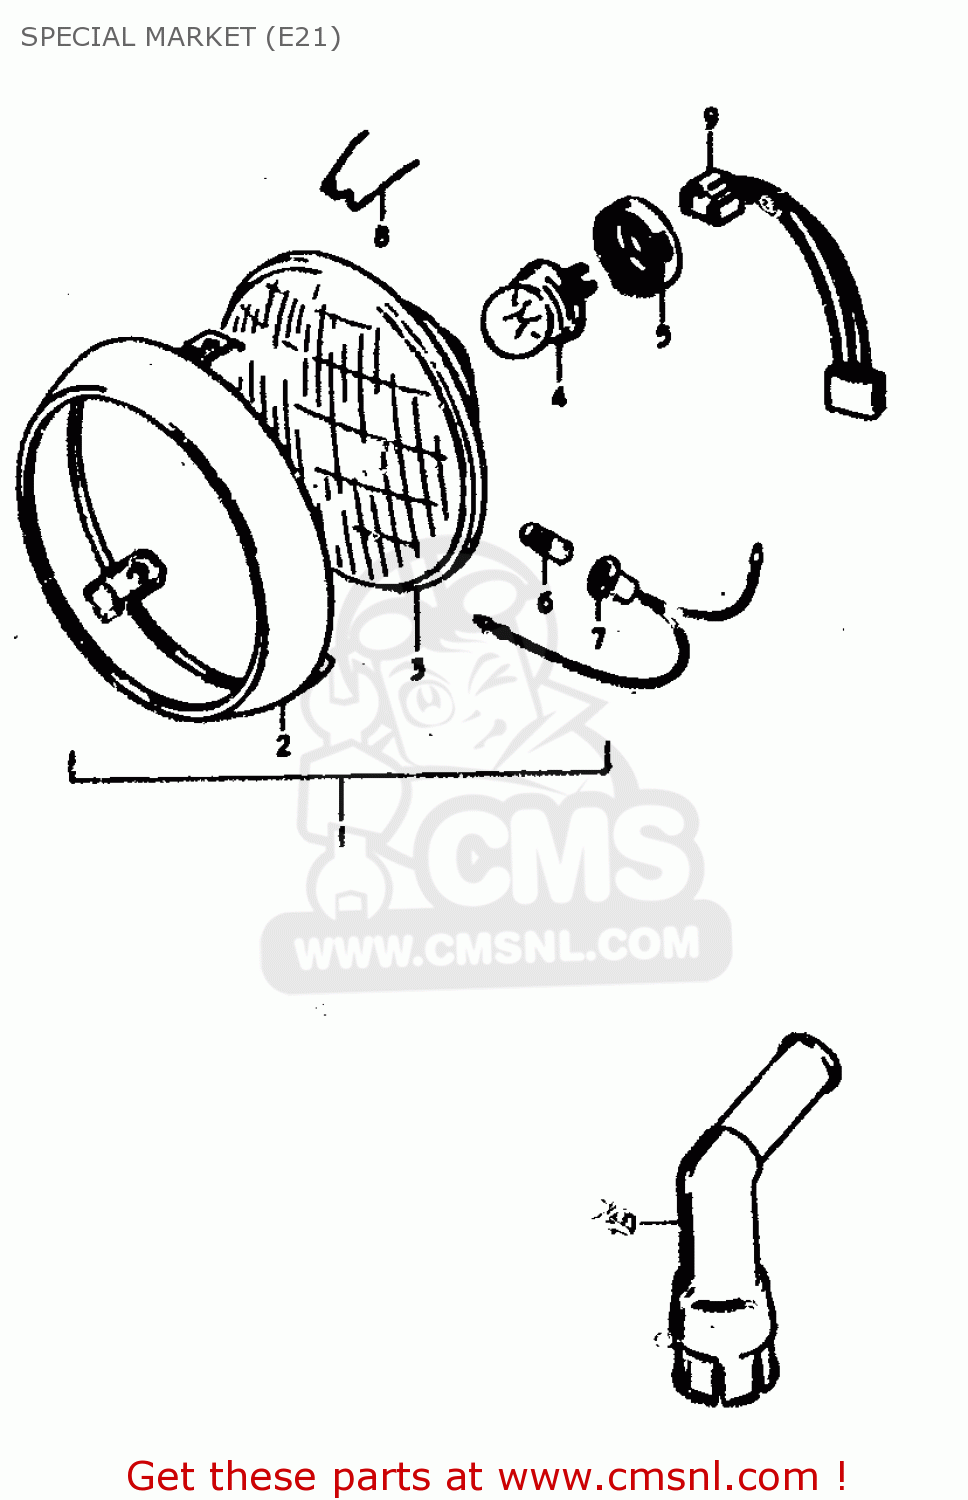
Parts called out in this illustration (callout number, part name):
1	HEADLAMP ASSY
2	RIM
3	UNIT
4	BULB(12V45/40W)
5	SETTER,BULB
6	BULB(12V4W)
7	SOCKET
8	SPRING,HEAD LA
9	LEAD WIRE,HEADLAMP
10	CAP, SPARK PLUG (S)
